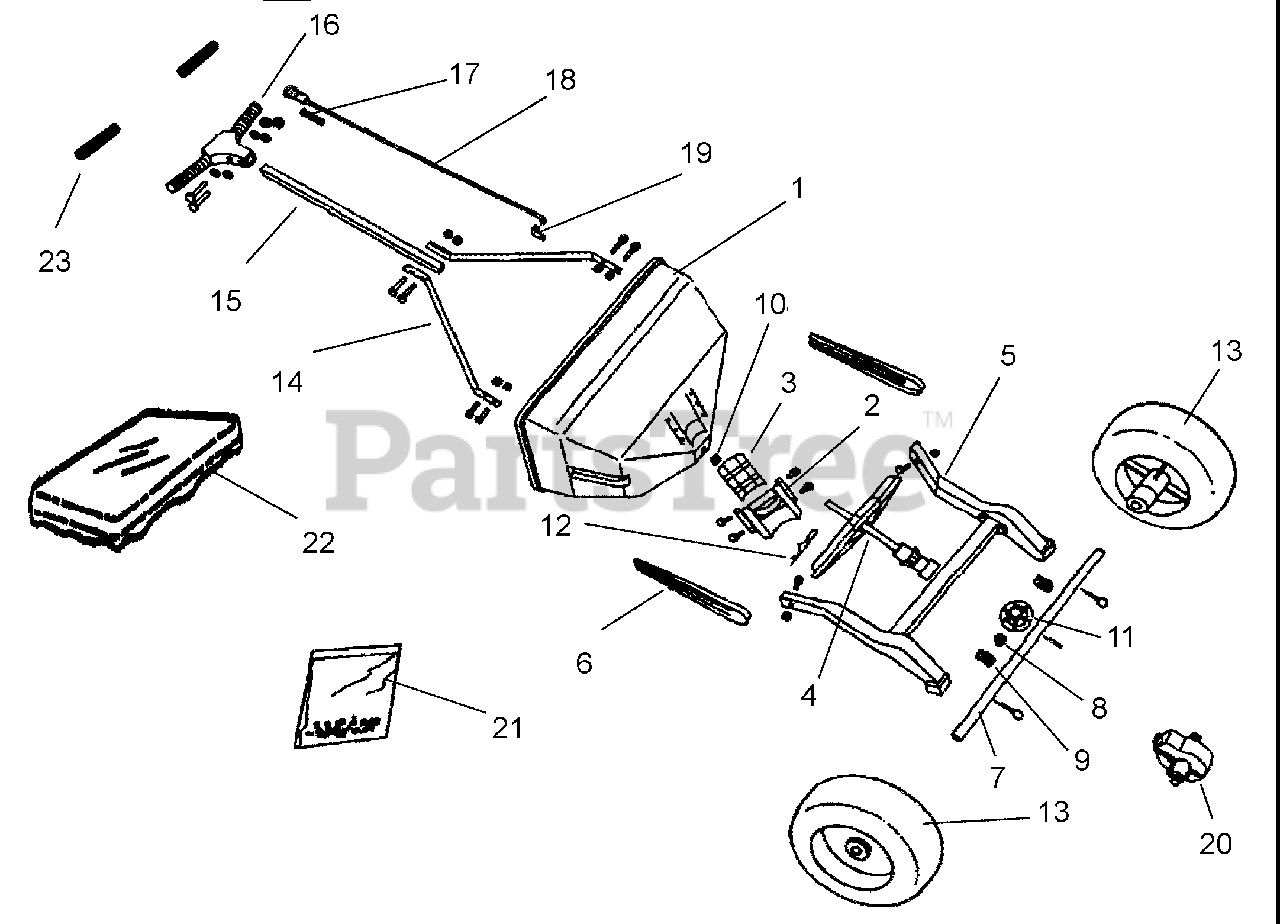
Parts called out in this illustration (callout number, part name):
1	HOPPER ASSY
2	RATE CAM & CHUTE ASSY
3	PLATE, SHUTOFF
4	IMPELLER ASSY
5	FRAME ASSY
6	LEGS
7	AXLE
8	AXLE COLLAR
10	BEARING
11	AXLE GEAR KIT
12	AGITATOR
13	WHEEL KIT
14	BRACE, HANDLE
15	TUBE, HANDLE
16	T-HANDLE ASSY
17	CONTROL KNOB SPRING
18	CONTROL BOX ASSY
19	CLIP
20	GEAR COVER ASSY
21	FASTENER KIT
22	COVER, HOPPER
23	GRIP, HANDLE
